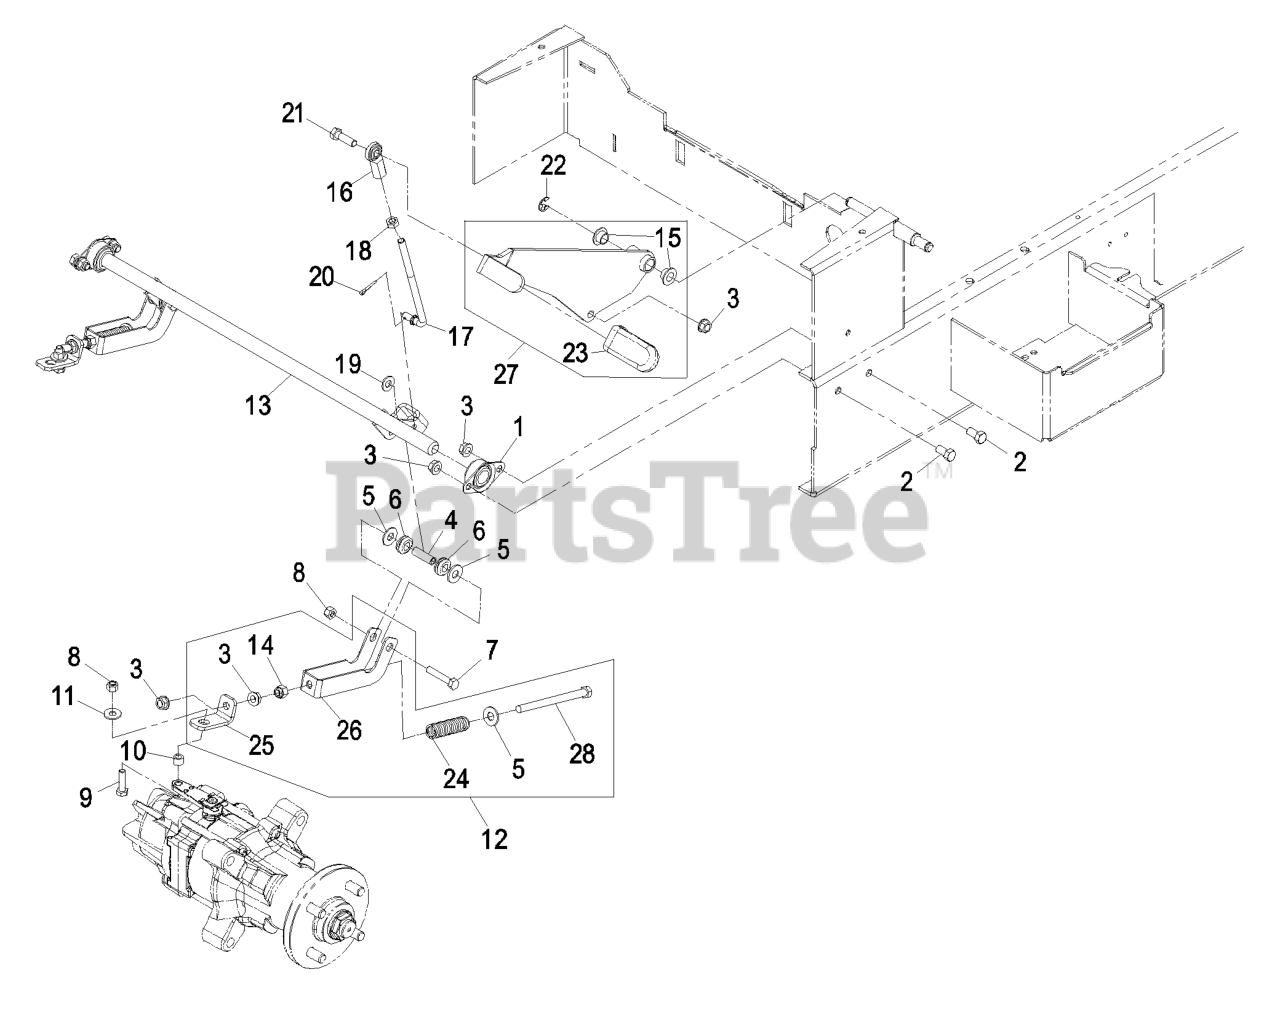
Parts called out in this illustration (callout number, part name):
1	BEARING-FLANGE, SIDE
2	SCREW-HH
3	NUT-HHF, WHIZ
4	SPACER,.438 OD X 1.312 (P
5	WASHER-FLAT
6	GROMMET
7	SCREW-HH
8	NUT-LOCK, NI
9	SCREW-HH
10	BUSHING, LOCATOR
11	WASHER-FLAT
12	ASM,BRAKE LINKAGE
13	WLD,BRAKE CROSS SHAFT
15	BEARING-CONTROL
16	JOINT-BALL, END
17	ROD,LINKAGE BRAKE (PLATED
18	NUT-HEX
19	WASHER-FLAT
20	PIN-COTTER
21	SCREW-HH
22	RING-RETAINING, EXTERNAL
23	GRIP-LEVER
24	SPRING,COMPRESSION
25	LINK,BRAKE (PLATED)
26	CLEVIS,BRAKE (PLATED)
27	ASM,BRAKE LEVER W/GRIP
28	BOLT-CAP
